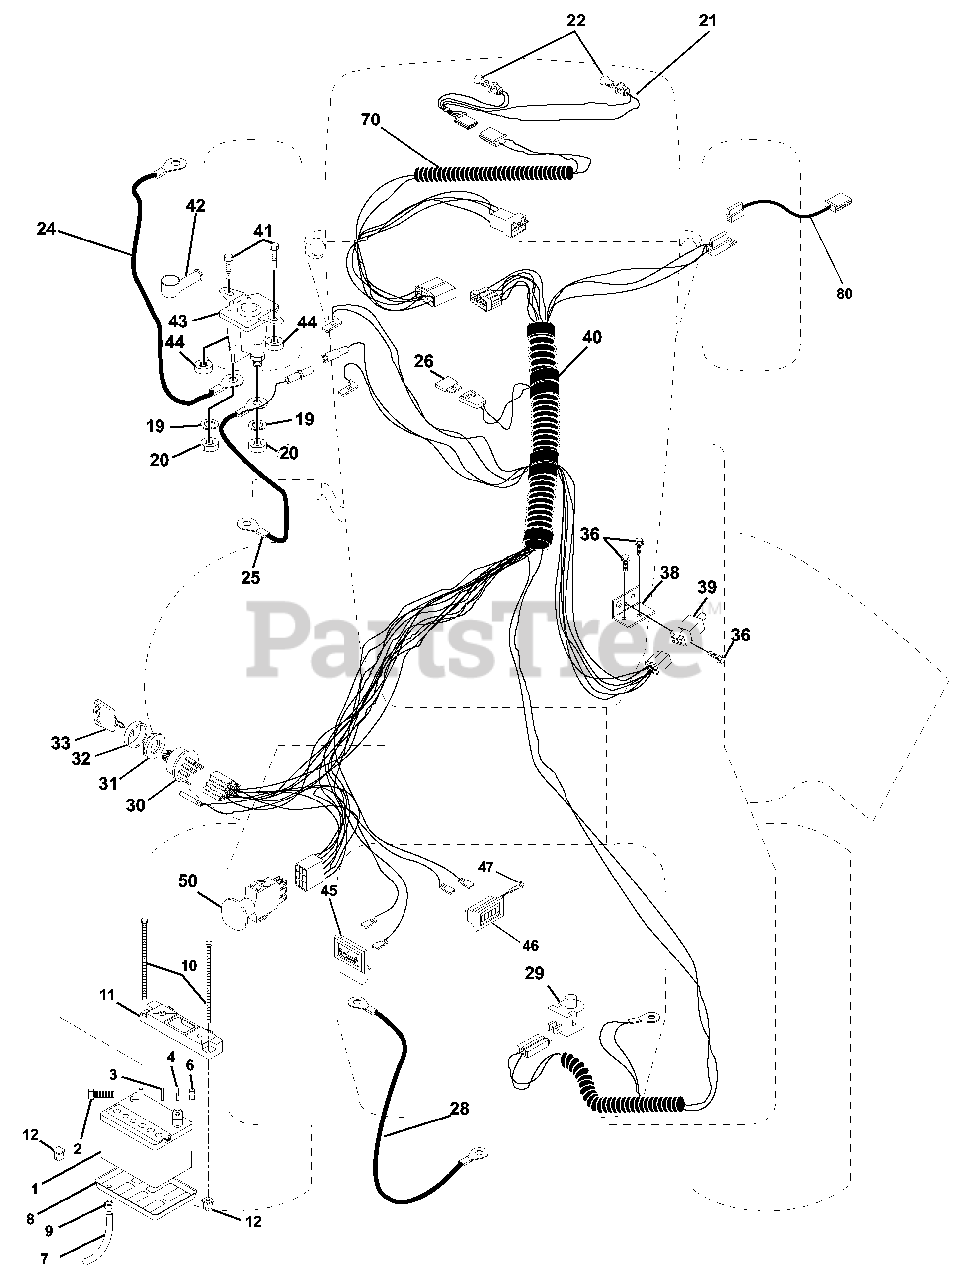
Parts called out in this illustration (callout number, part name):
1	Battery 12 Volt 30 AMP
2	Bolt Hex Hd 1/4-20unc X 3/4
3	Washer 9/32 X 5/8 X 16 Ga.
4	Washer Lock Hvy Helical 1/4
6	Nut Fin Hex 1/4-20 Unc
7	Tube Plastic 46"
8	Tray, Battery 7.80 x 5.25 blk
9	Clamp Hose Olive
10	Bolt, Btr, Front, 1/4-20 x 7.5 Zinc
11	Holddown, Battery Dash Mount
12	Nut, Push, Nylon 1/4" Battery Frt
15	Fastener Snap-In
19	Washer Lock 1/4
20	Nut Jam Hex 1/4-20 Unc
21	Harness Asm Light W/4152j
22	Bulb Light #1156
24	Cable Battery 6 Ga 11" red
25	Cable 6 Ga. Red 22" w/16" Wire
26	Fuse 30 AMP Auto Green
28	Cable, Ground 21" Blk 6 Ga. 90T
29	Switch Plunger Nc Gray
30	Switch Ign 4 pos w/lights
31	Nut Ignition
32	Cover Sw Ignition
33	Key Ign Modleded Generic
36	Screw Tap Hex #10-24unc X 1/2
38	Bracket, Switch, Interlock
39	Switch Intlk Clutch Red 4 Term
40	Harness Ign. Elec. HMLT P/L
41	Bolt Blk Fin Hex 1/4 - 20 x 1/2
42	Cover Terminal Red
43	Solenoid
44	Nut Keps Hex 1/4-20 Unc
45	Ammeter Rectangular 6 Amp
46	Meter Hour
47	Screw 10-24 x 1/2 Black
50	Switch PTO 3 PTD Black
70	Harness, Eng.
80	Harness Clutch EVX
